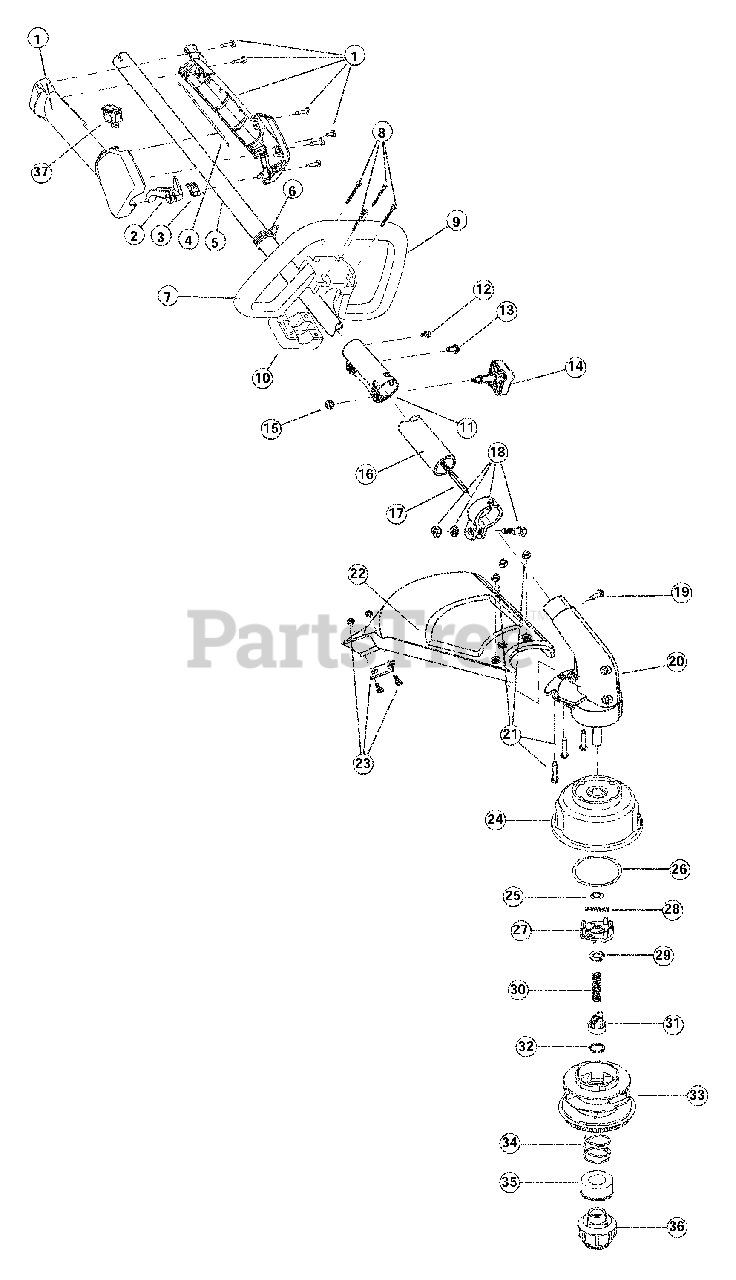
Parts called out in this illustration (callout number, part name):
1	Throttle Housing Assembly
2	Throttle Trigger
3	Throttle Trigger Spring
4	Throttle Cable Assembly
5	Upper Drive Shaft Housing Assembly
6	Harness Clip
7	Deluxe D-Handle Assembly
9	Deluxe D-Handle
10	Bottom Clamp
11	Split-Boom Coupler
14	Adjustment Knob
15	Knob Retaining Bolt
16	Lower Drive Shaft Housing Assembly
17	Lower Flexible Drive Shaft
18	Lower Clamp Assembly
19	Anti-Rotation Screw
20	Gear Box Assembly
21	Shield Mounting Hardware
22	Shield and Blade Assembly
23	Blade Assembly
24	Outer Spool and Eyelet Assembly w/ Retainer
26	Thrust Washer
28	Small Spring
33	Inner Reel
34	Large Spring
36	Bump Head Knob Assembly
